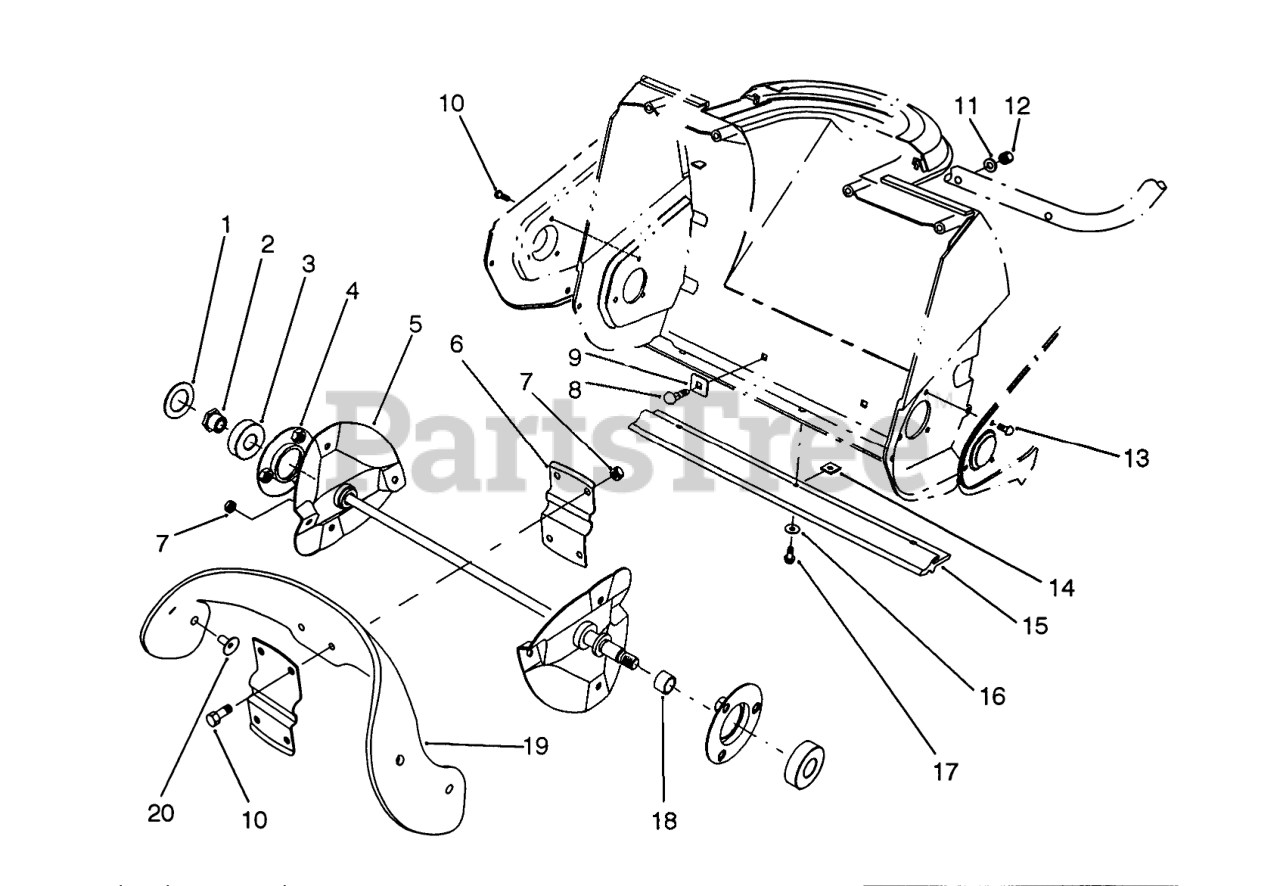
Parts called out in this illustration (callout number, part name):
1	WASHER-RUBBER
3	BEARING-BALL
4	FLANGE BEARING ASM
5	Rotor
6	Support-Rotor
7	NUT-LOCK, NI
8	SCREW-CARR
9	WASHER-SQUARE
10	SCREW-HHF
11	WASHER
12	NUT-LOCK, NI
13	SCREW-HH
14	NUT-CLIP, U
15	SCRAPER
16	WASHER-FLAT
17	SCREW-HWHTF
18	SPACER
19	BLADE-ROTOR
20	SCREW
